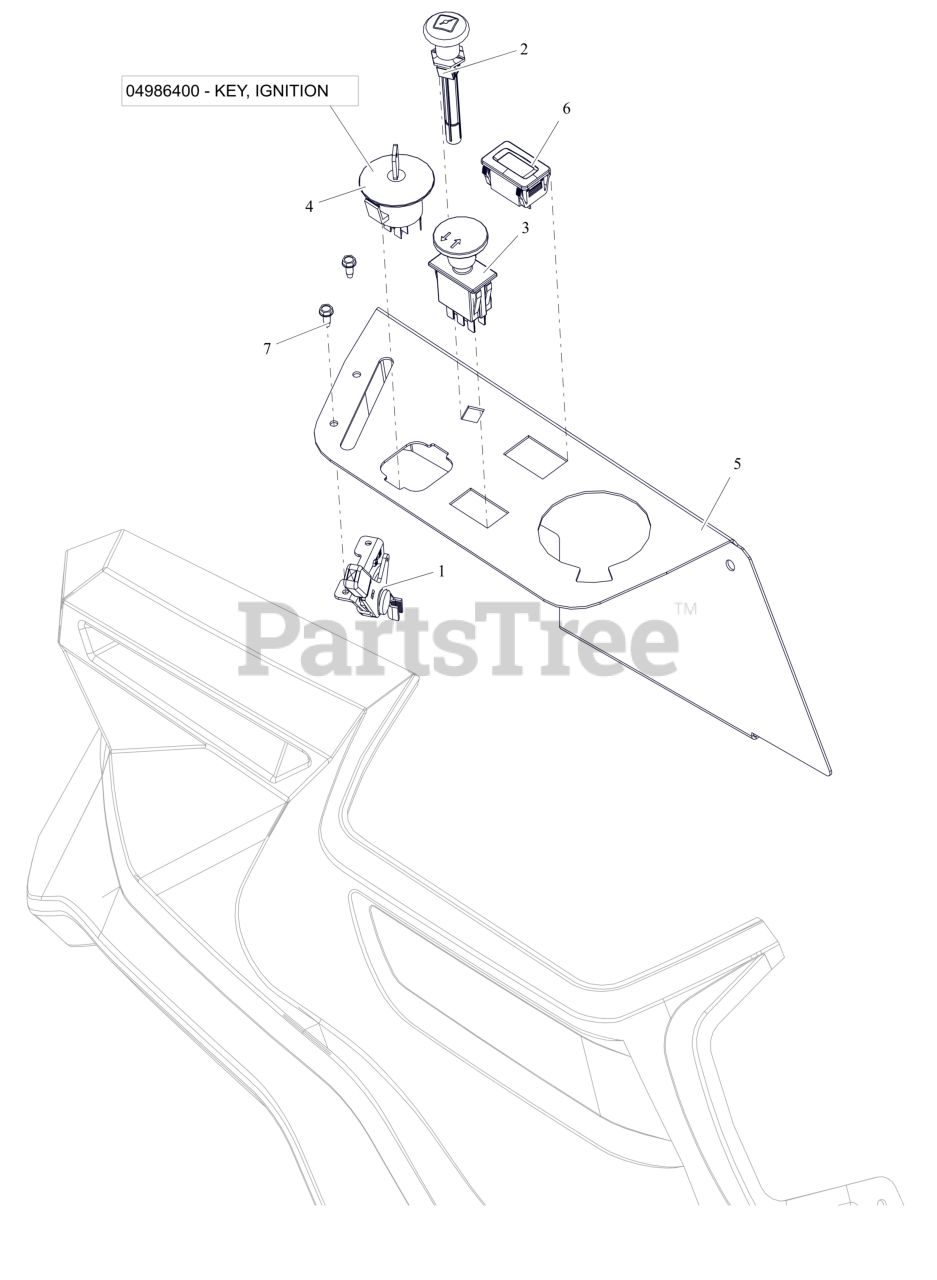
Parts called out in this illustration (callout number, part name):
1	CABLE - THROTTLE CONTROL
2	CABLE - CHOKE, SNAP-IN
3	SWITCH, CLUTCH (YELLOW)
4	KEYSWITCH-IGNITION 4 POS
4	KEY, IGNITION
5	PANEL, RIGHT SIDE FENDER MOUNT
6	HOUR METER
7	SCR,TAP #10-24X.50 HWH TR ZCC
